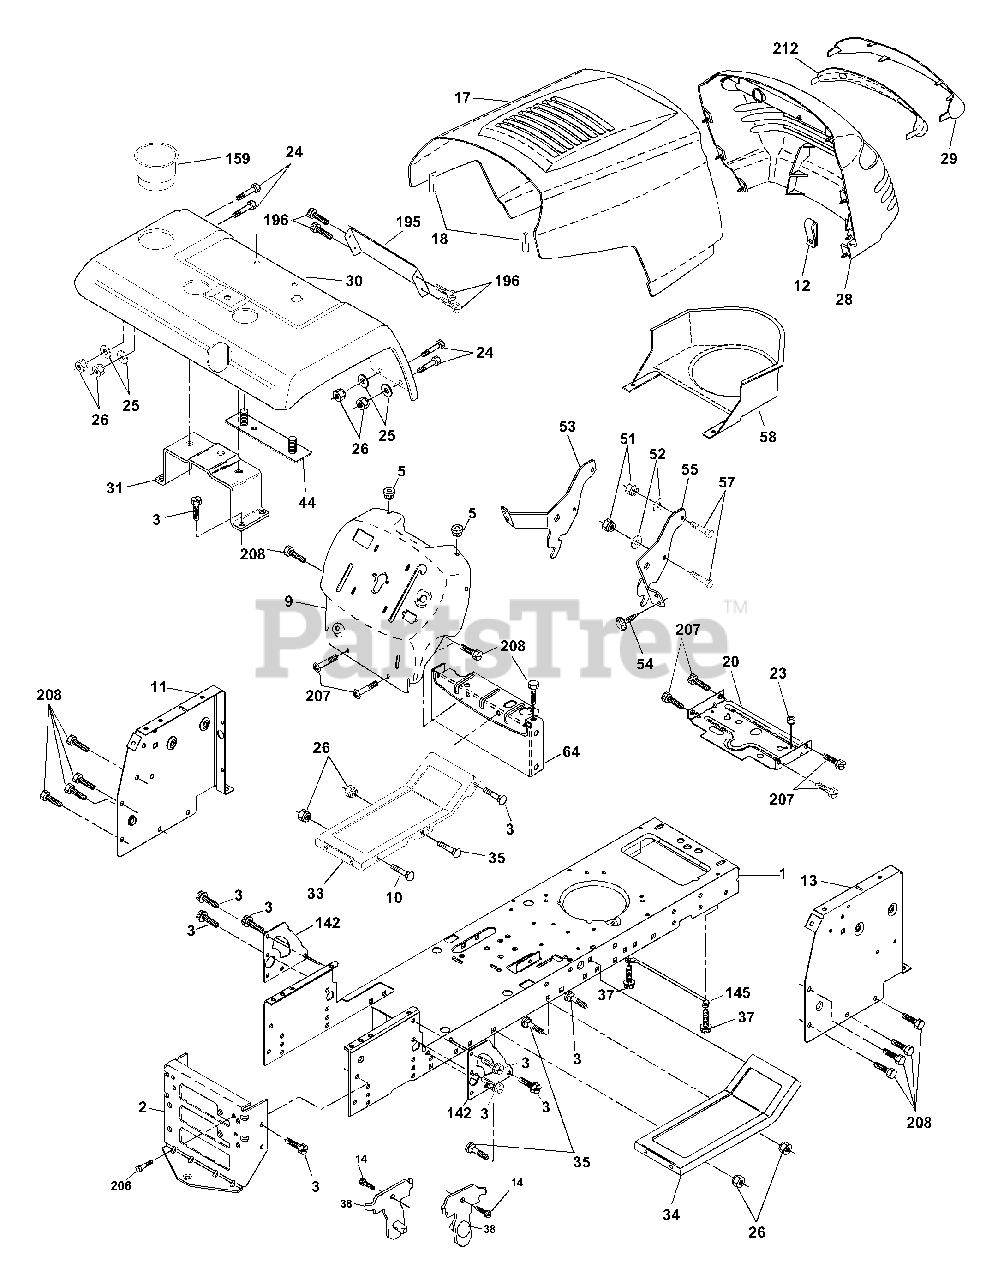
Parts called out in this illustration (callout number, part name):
1	Chassis Stamping
3	Screw 3/8-16x3/4
9	Dashboard
10	Bolt Rdhd Sqnk 3/8-16 Unc x 1
11	Panel Dash Lh
12	Clip Tinnerman Grille
13	Panel Dash Rh
14	Screw Thdrol 3/8-16 x 1/2
17	Hood
20	Plate Mtg Battery/Fuel Tank
24	Bolt 3/8-16 Unc x 1 Gr. 5
25	Washer 13/32 x 13/16 x 12 Ga.
26	Nut Lock w/Insert 3/8-16 UNC
28	Grille Lens Asm
29	Lens
30	Fender
31	Bracket
33	Foot Rest, L.H.
34	Foot Rest, R.H.
35	Bolt Rdhd Sht Sqnk 3/8-16 x 3/4
37	Screw Thdrol 5/16-18 x 1/2
38	Bracket Asm Pivot Mower Rear
44	Strap Asm. Fender
51	Nut Lock w/Insert 1/4-20
52	Washer 9/32 x 7/8 x 16 Ga.
53	Bracket Grille Lh
54	Screw Hex Wshd 8-18 x 7/8
55	Bracket Grille Rh
57	Bolt Fin Hex 1/4-20 Unc x 3/4
64	Dash Lower Stlt
142	Plate Reinforcement Stlt
145	Rod Pivot Chassis Hood
159	Cupholder YTGT Grey
195	Panel Pnt Fender YT/GT
196	Screw Tap Tite 1/4-20 x 1/2
206	Bolt Shoulder 5/16-18 TT
207	Screw Thdrol 5/16-18 x 1/2 TYTT
208	Screw Thdrol 3/8-16 x 1/2 Ty-TT
212	Insert Lens Reflect
